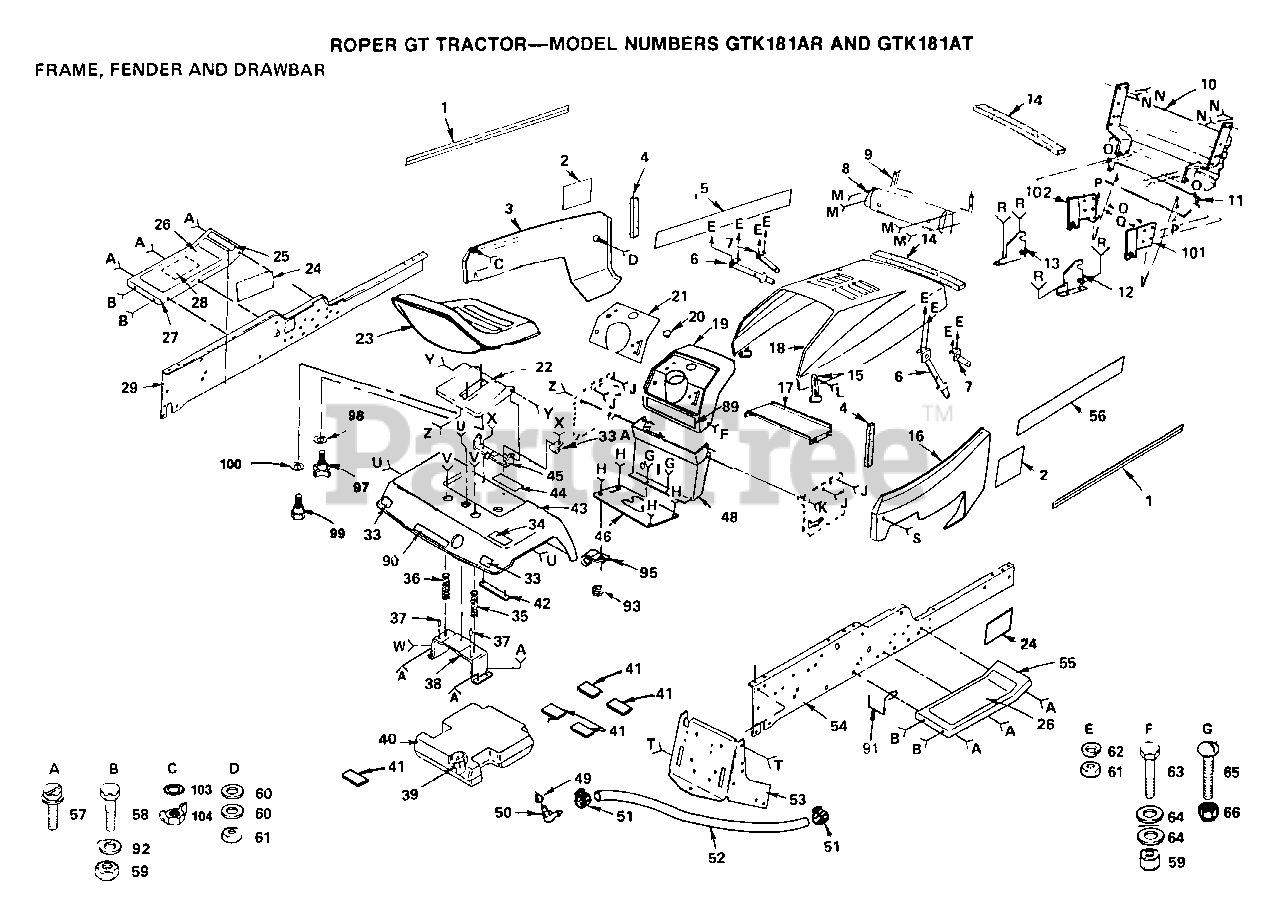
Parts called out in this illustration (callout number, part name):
4	FOAM STRIP T
9	LENS LT
12	SUPPORT RH YTH
13	SUPPORT LH YTH
14	FOAM STRIP T
15	HOOD LATCH T
20	PLUG-DASH T
21	DECAL-DASHBOARD (GTK181AT ONLY)
28	DECAL T
33	REFLECTOR-TAIL YT
34	DECAL-CAUTION
37	NUT-PUSH YT
41	PAD-SPACER LT
48	DASH ASSEMBLY
49	BUSHING OUTLET T
50	No Desciption for Part
57	SCREW
60	WASHER PM
63	BOLT
64	WASHER
65	SCREW
91	BELT RETAINER GT
92	WASHER
96	SCREW LT
97	"KNOB 1/2"" YT"
99	BOLT T
101	SUPPORT LH YTH
102	SUPPORT RH YTH
103	LOCKWASHER GT
